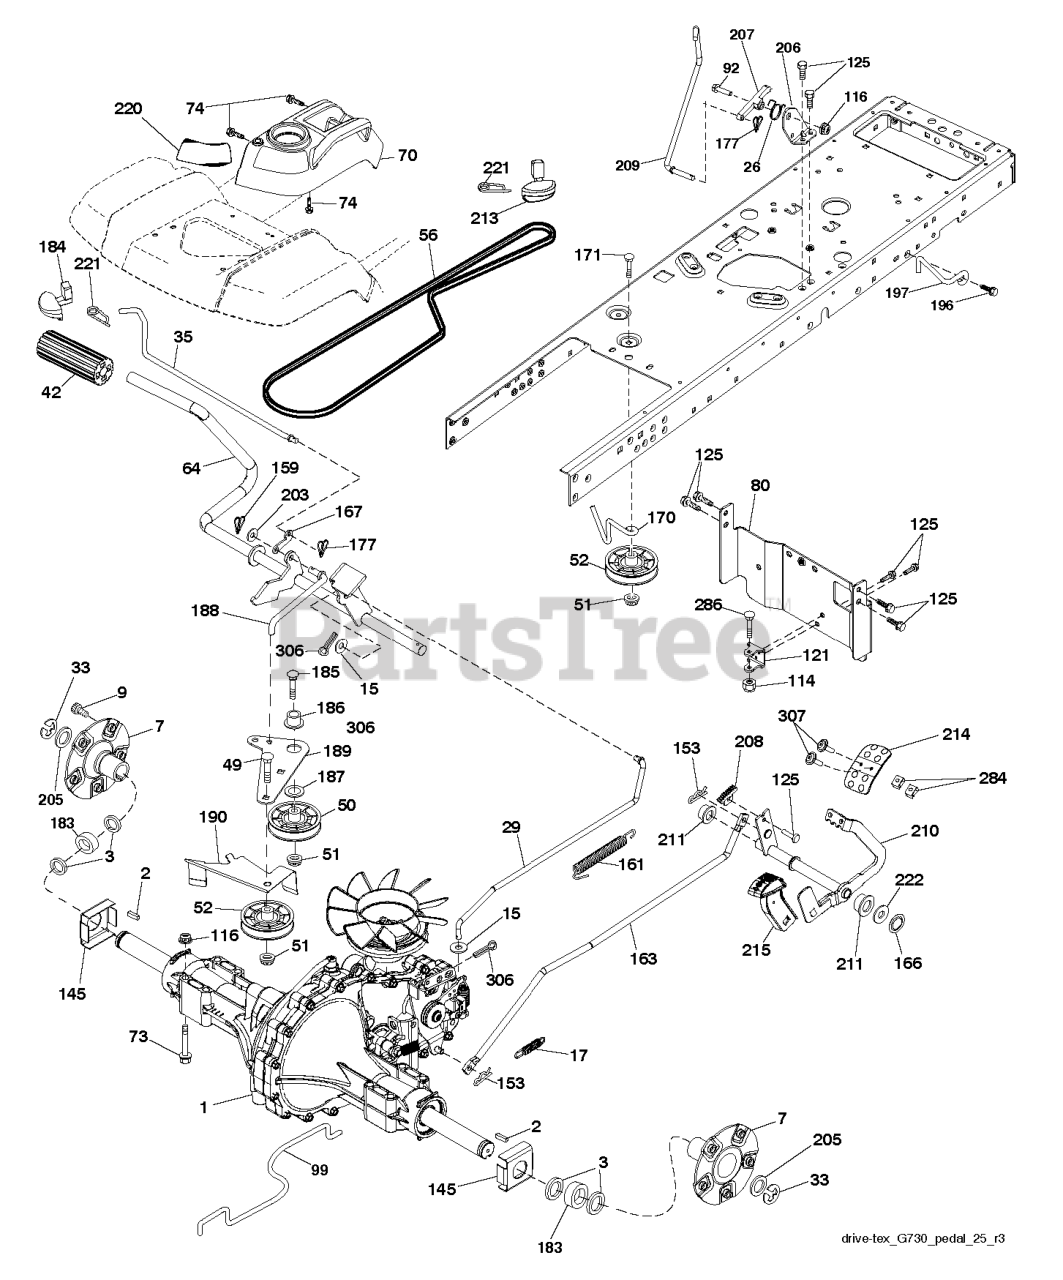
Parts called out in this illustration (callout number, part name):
2	KEY 1/4 X 2.5
7	HUB.ASM.WHEEL.REAR.23"TEX
9	HUB BOLT
15	WASHER
17	SPRING.BRAKE.HG3000/3500
26	SPRING.RETURN.CRUISE
33	E RING HYT
35	ROD .BRAKE. PARKING. GT. HUSQ.
42	PEDAL COVER T
48	BOLT.3/8-16X1.50
50	IDLER.FLAT.910.OFFSET
51	NUT LOCK FLG 3/8-16 UNC
52	IDLER.V-GROOVE.910.OFFSET
56	V-BELT.GROUND.DRIVE.
64	SHAFT.ASM.PEDAL.BRK.CNTR
70	CONSOLE.ASM.RH.GT.FC.HUSQ
73	BOLT HEX FLGHD 5/16-18X3 GR. 5
74	SCREW.HI-LO.CONSOLE
80	STRAP.TORQUE.YT.G700
92	BOLT
99	SPRING.BYPASS.YT.G700
114	NUT.71038.31-18.HEX.NYLOCK
116	NUT LOCK HEX FLANGE 5/16-18
121	BRACKET STRAP TORQUE
125	SCREW
145	WASHER.AXLE.FLANGE.HG-3000
153	RETAINER M
159	COTTER PIN
160	RETAINER CLIP
161	SPRING, RETURN LT
163	ROD PEDAL CONTROL
166	NUT.PUSH.625
167	LATCH.BRAKE.SPRING
184	HANDLE.PARKING.BRAKE.H (BLK)
186	SPACER.RETAINER
187	WASHER 12/32X2X10GA
188	RP.LINK.CLUTCH.GROUND.DRIVE
189	BELLCRANK.GROUND.DRIVE.TRAPPED
190	KEEPER BELLCRANK ROUND DRIVE
196	SCREW 3/8-16X1
197	CLUTCH.ANTIROTATION.WIREFORM.
203	WASHER
206	BRACKET.MOUNT.CRUISE.LATCH
207	LATCH.CONTROL.CRUISE
208	GEAR.SECTOR.CONTROL.CR
209	ROD.CONTROL.CRUISE.GT.
210	ROCKER.ASM.PEDAL.CONTR
211	BEARING.NYLON
213	KNOB.CONTROL.CRUSIE.HU
214	PEDAL.FORWARD.HUSQVARNA.DEALER
215	PEDAL.REVERSE.TEX.GT.4
220	REFLECTOR.RH.TEX GT
221	RETAINER.SPRING.CLIP.H
222	WASHER 21/32 X 1-1/4 X 10 GA.
284	NUT.U-CHNL.1/4-20.550DP.350PNL
286	BOLT.5/16-18X2.5
306	PIN COTTER
307	SCREW.MACHINE.CR.1/4-20
323	SLEEVE.BELLCRANK
